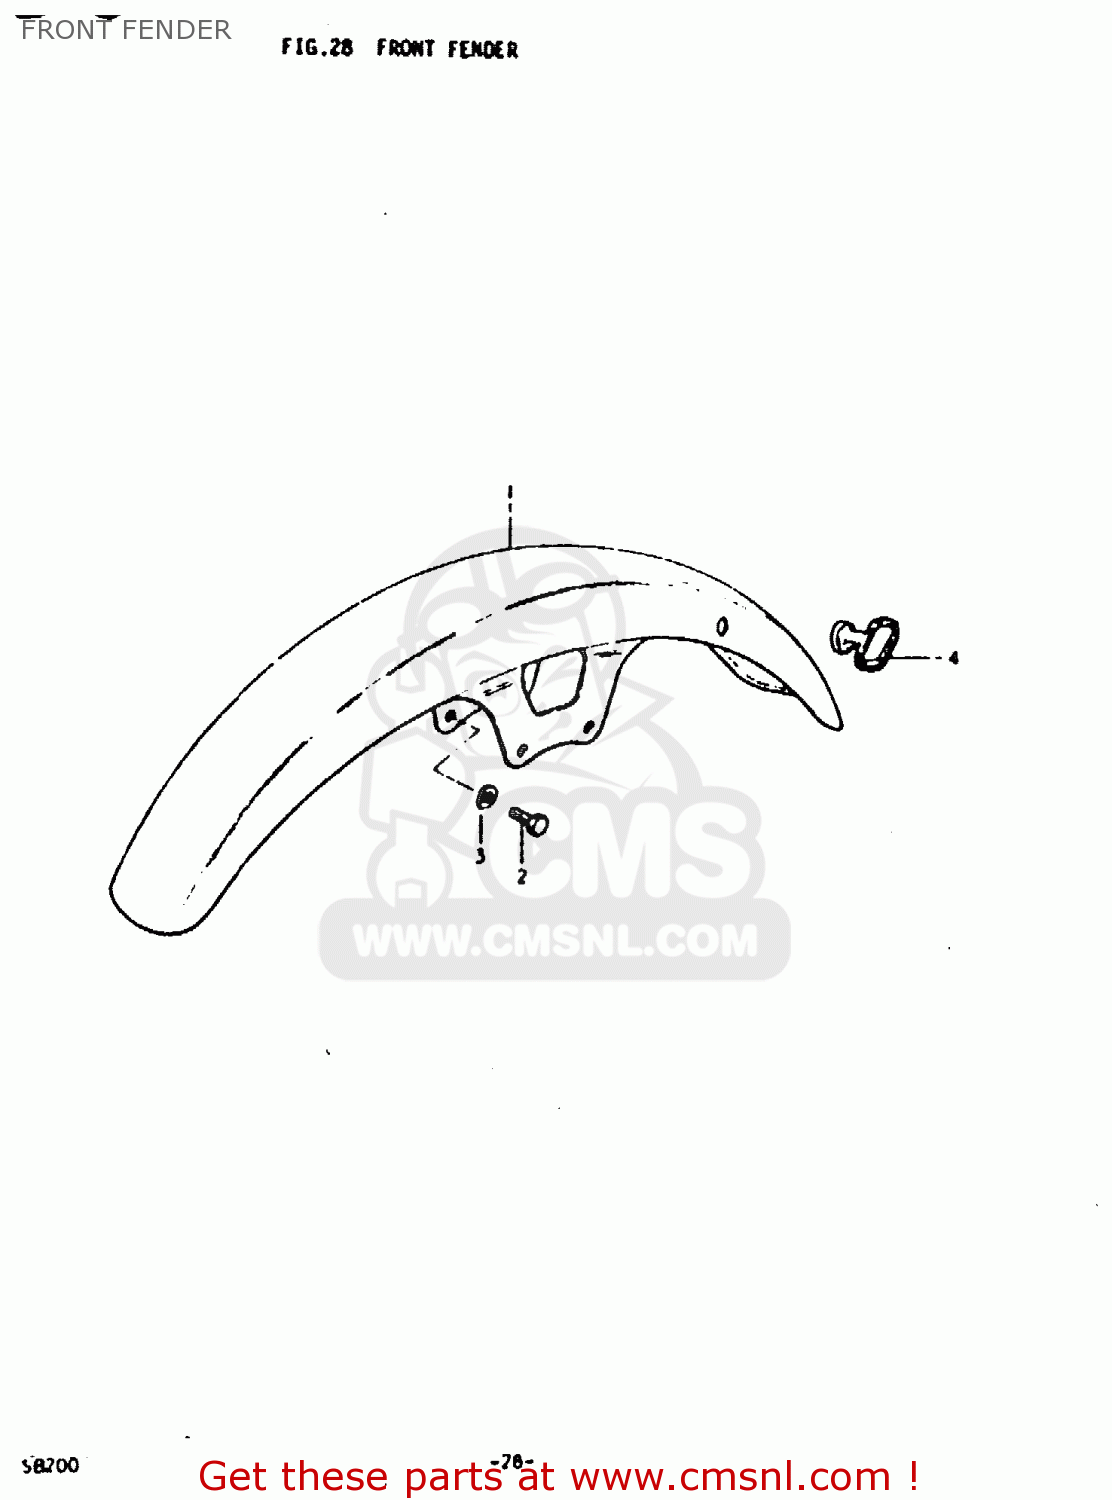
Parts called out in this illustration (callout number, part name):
1	FENDER, FRONT
2	BOLT
3	LOCK WASHER
4	GUIDE,CABLE
